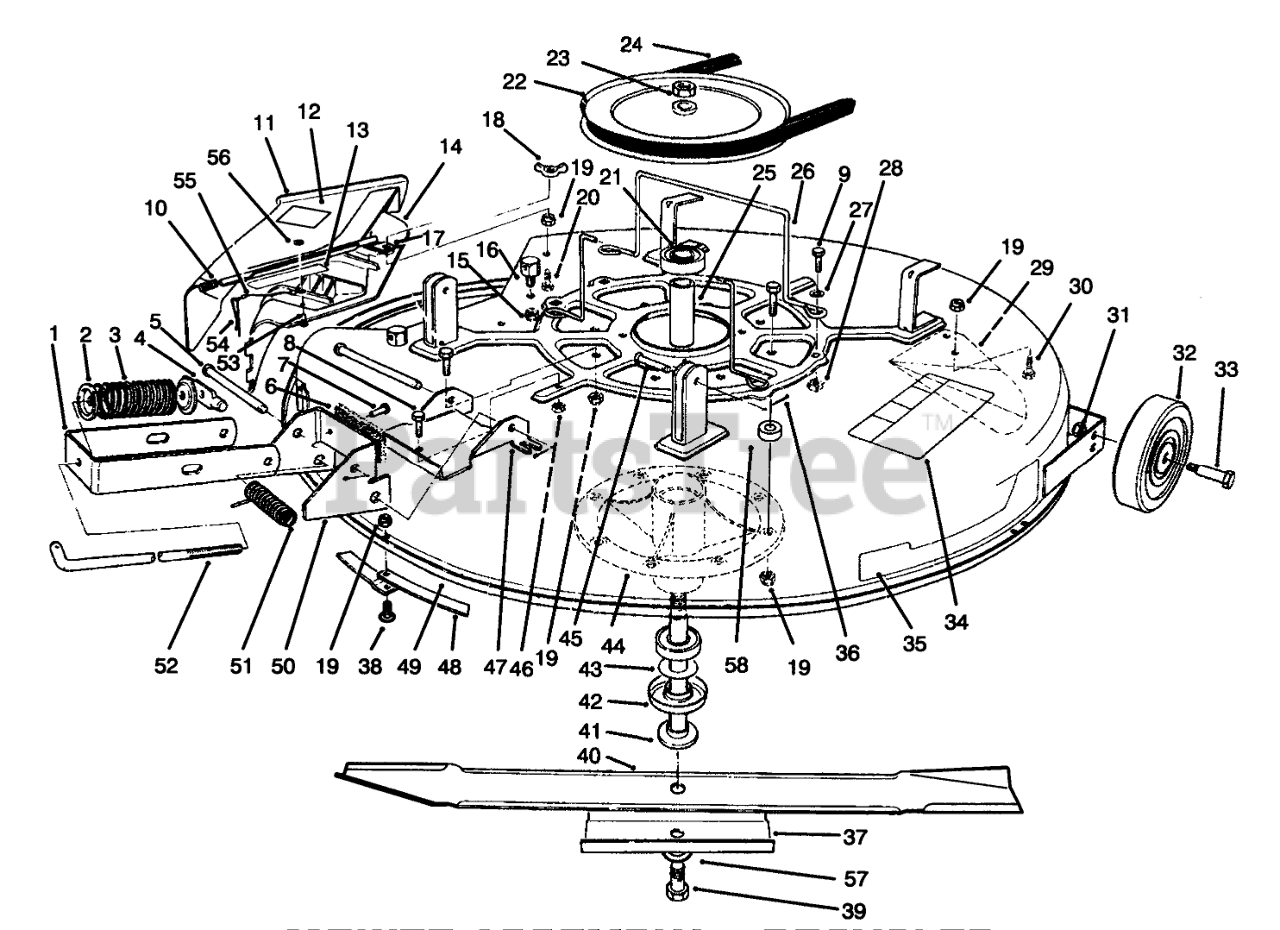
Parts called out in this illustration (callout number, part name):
1	Bracket-Engagement
2	RETAINER-SPR. TOP
3	SPRING-COMPRESSION
4	SHAFT-DECK ADJ.
5	PIN-CLEVIS
6	PAD-BRAKE
7	RIVET-BLIND
8	SCREW-HH
9	SCREW-HH
10	SPRING
11	Assembly-Deflector (Incl. Ref. #12)
12	DECAL-DANGER
13	DECAL-DANGER
14	Assy.-Cover, Discharge (Incl. Ref. #53-56)
15	NUT-LOCK, NI
16	POST-PIVOT
17	Brace-Cover, Rear
18	NUT-WING
19	NUT-LOCK, NI
20	SCREW-HH
21	BEARING-BALL
22	PULLEY
23	NUT-HEX
24	V-BELT, DECK
25	SPACER-BEARING
26	GUIDE-BELT
27	WASHER-PLAIN
28	NUT-RETAINER
29	Kicker
30	SCREW-HH
31	NUT-LOCK, NI
32	WHEEL-DECK
33	BOLT-WHEEL
34	DECAL-DANGER
35	DECAL-RECYCLER
36	PIN-COTTER
37	STIFFENER
38	SCREW-PPH
39	SCREW-HH
40	Blade
41	SHAFT-SPINDLE
42	SHIELD-BEARING
43	SPACER-HARDNED
44	SPINDLE
45	PIN-CLEVIS
46	NUT-HEX
47	Plate-Deck, Brake Mtg.
48	RING-DECK
49	Deck-Cutting
50	Assembly-Brake (Incl. Ref. #6-7)
51	SPRING
52	ROD-ENGAGEMENT
53	RIVET-BLIND
54	PIN-LOCKING, CHUTE
55	LANYARD
56	WASHER-PLAIN
57	WASHER-BELLEVILLE
58	ISOLATER-SEAT
